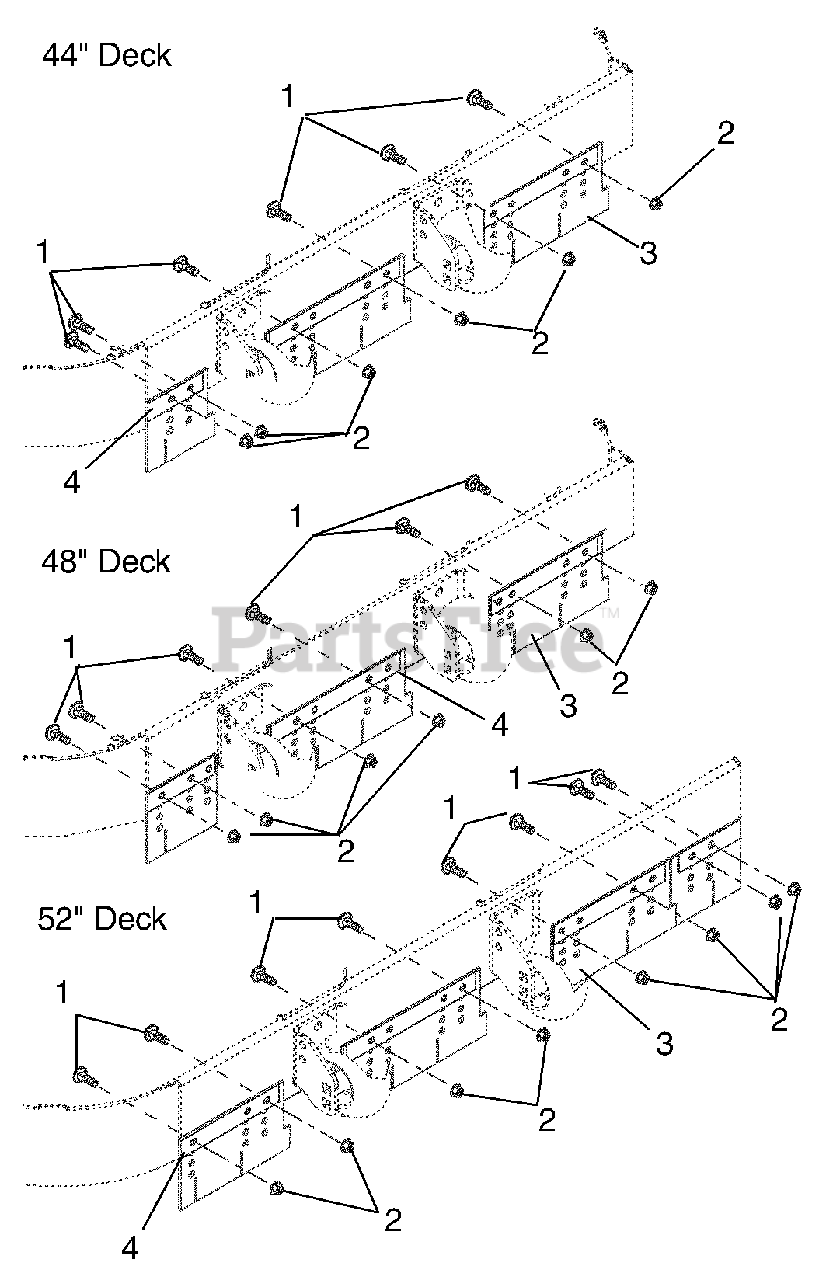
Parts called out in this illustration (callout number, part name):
1	@BLT-RDHDSQNK .38-16X1.00 G5YZ
2	@NUT-LK-TOP-FLG .38-16 YWZC
3	SKIRT, RUBBER STRIPER
4	BAR, STRIPER
